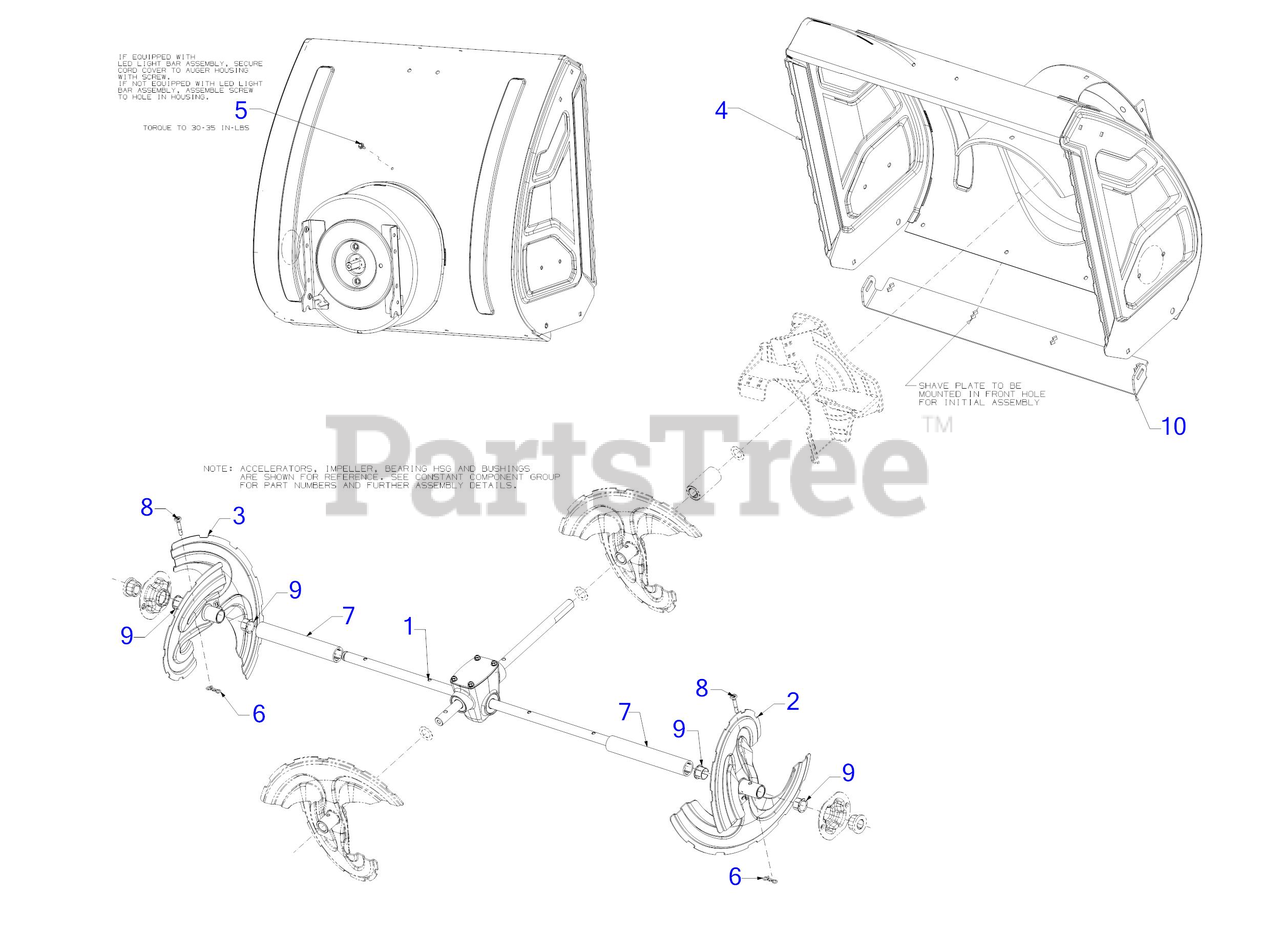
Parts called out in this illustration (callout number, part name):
1	28" AUGER GEARBOX ASSEMBLY
5	SCREW M6-1 x .625
6	BOW TIE COTTER PIN 1/4-5/16
8	SHEAR PIN .25 X 1.50 (3 STAGE)
9	FLANGE BUSHING
